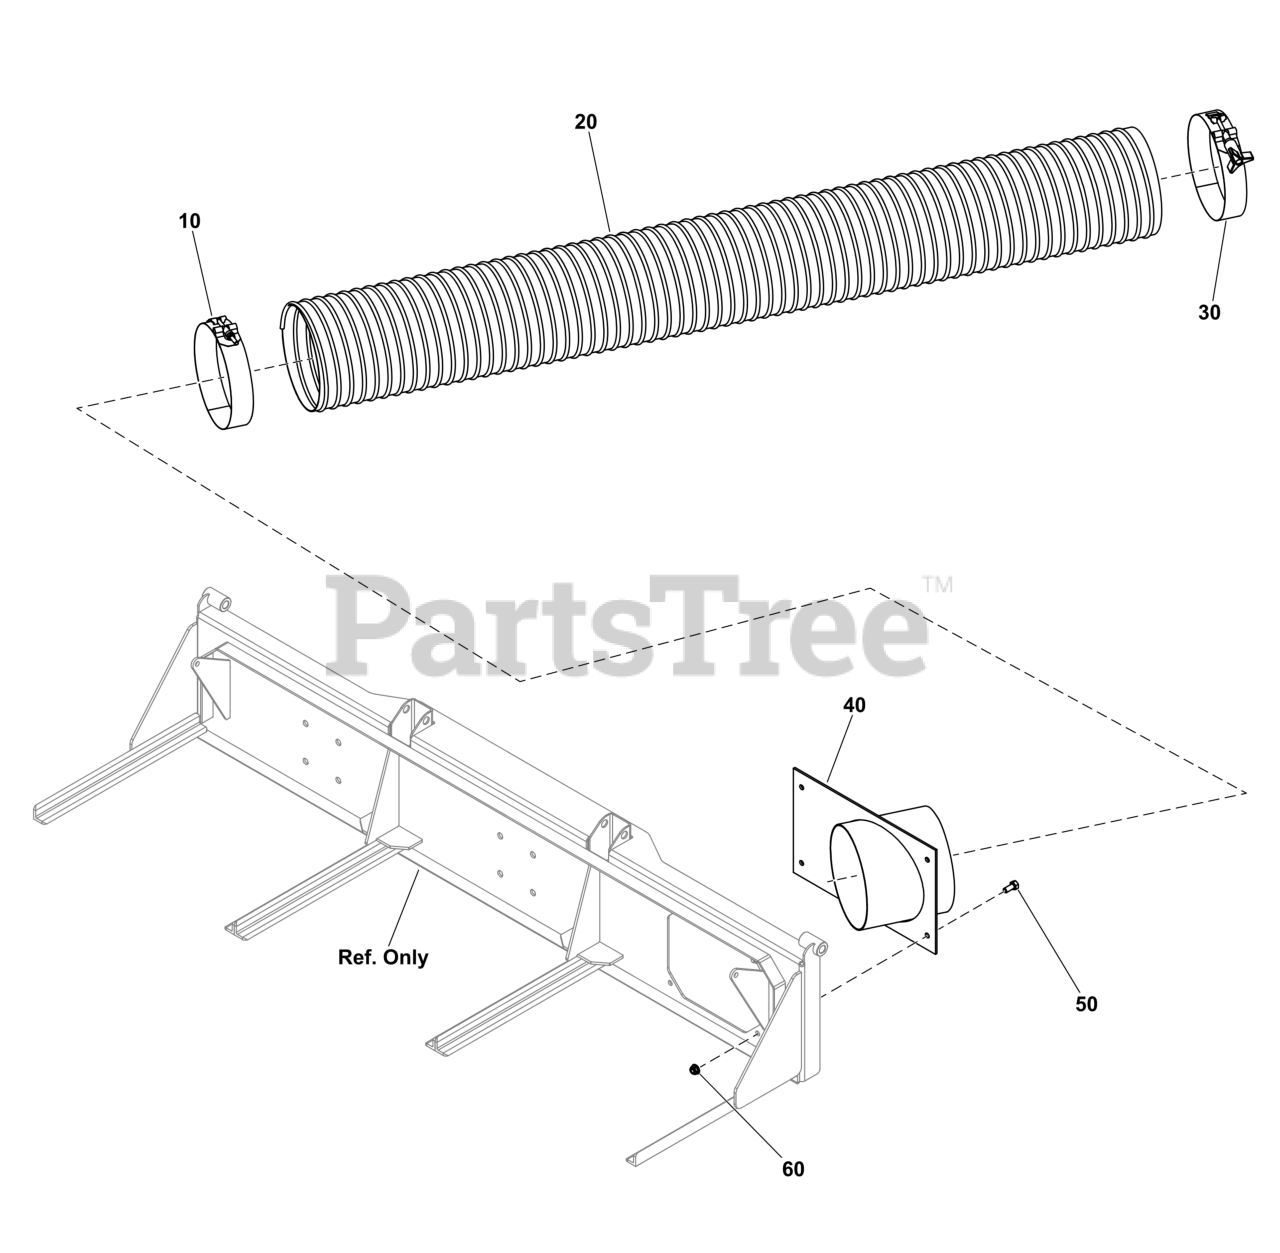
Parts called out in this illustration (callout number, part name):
10	CLAMP, HOSE, UPPER
20	HOSE, FLEXIBLE, 7"
30	CLAMP, HOSE, LOWER
40	WELD, INLET BLOWER 3-
50	BOLT, 5/16-18 X 3/4"
60	NUT
